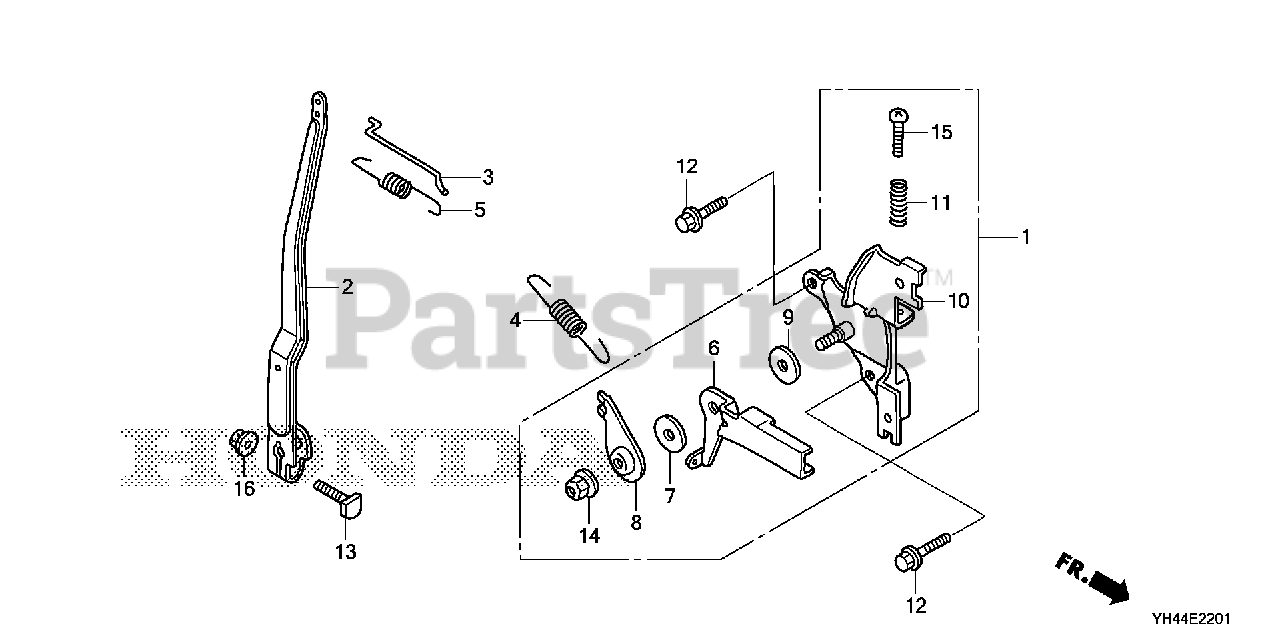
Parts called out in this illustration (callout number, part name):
1	CONTROL ASSY.
2	ARM, GOVERNOR
3	ROD, GOVERNOR
4	SPRING, GOVERNOR
5	SPRING, THROTTLE RETURN
6	LEVER, CONTROL
7	SPRING, LEVER
8	WASHER, CONTROL LEVER
9	SPACER, CONTROL LEVER
10	BASE, CONTROL
11	SPRING, CONTROL ADJUSTING
12	BOLT, FLANGE (5X12)
13	BOLT, GOVERNOR ARM
14	NUT, SELF-LOCK (6MM)
15	SCREW, PAN (5X20)
16	NUT, FLANGE (6MM)
